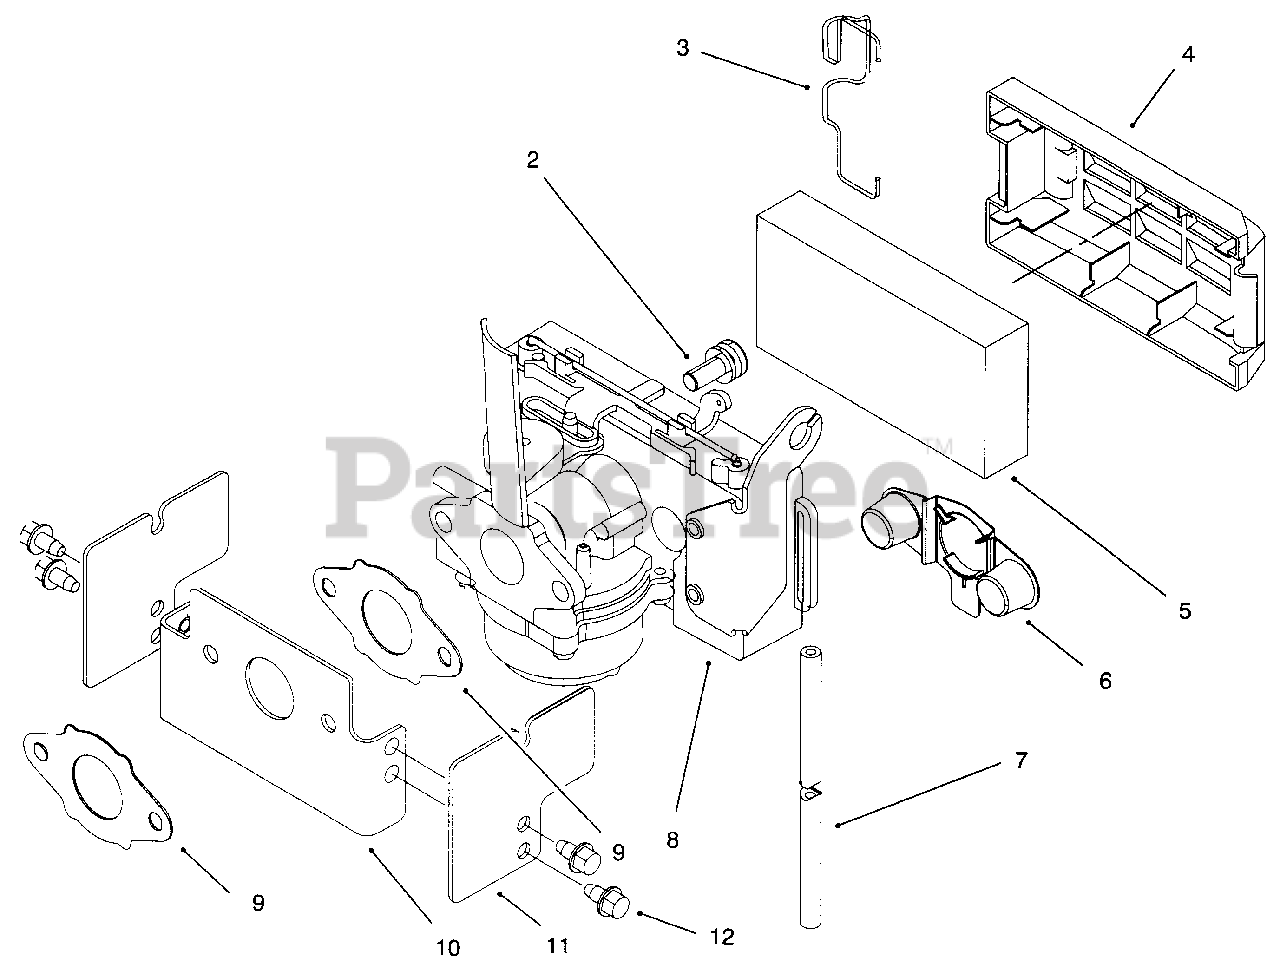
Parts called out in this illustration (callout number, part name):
3	Retainer-Filter
4	Cover-Air Cleaner
5	Element-Filter Air
6	Shield-Fuel
7	Hose-Primer
8	Carburetor Assembly (Incl. Ref. #9)
9	Gasket-Carburetor
10	Shield-Carburetor (Intl.)
11	Shield-Governor V (Intl.)
